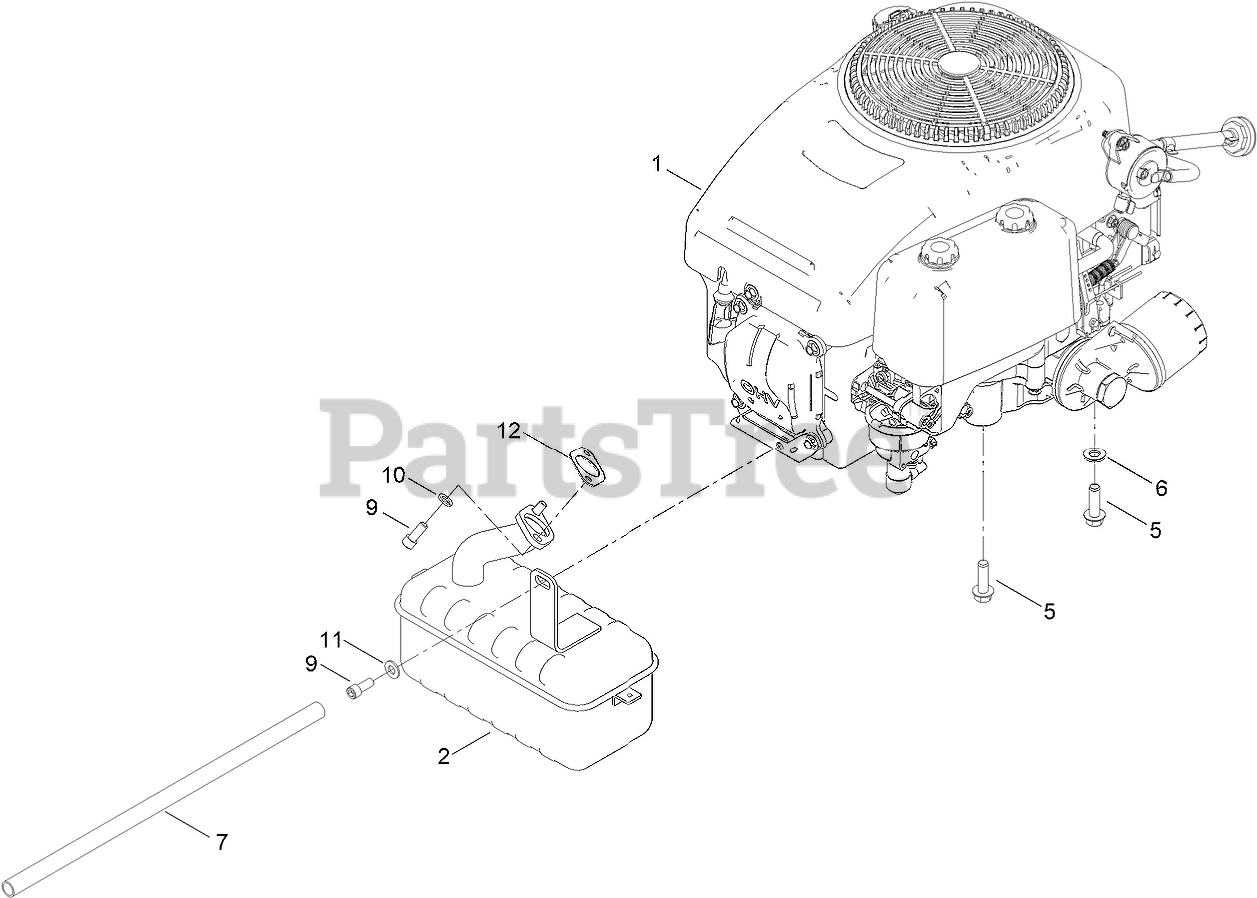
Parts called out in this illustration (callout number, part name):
1	ENGINE-1P92F-1
2	MUFFLER
5	SCREW-HWH, THD ROLL
6	WASHER-FLAT
7	TUBE-DRAIN, OIL
9	SCREW-HSH
10	WASHER-LOCK
11	WASHER-PLAIN
12	GASKET-EXHAUST
